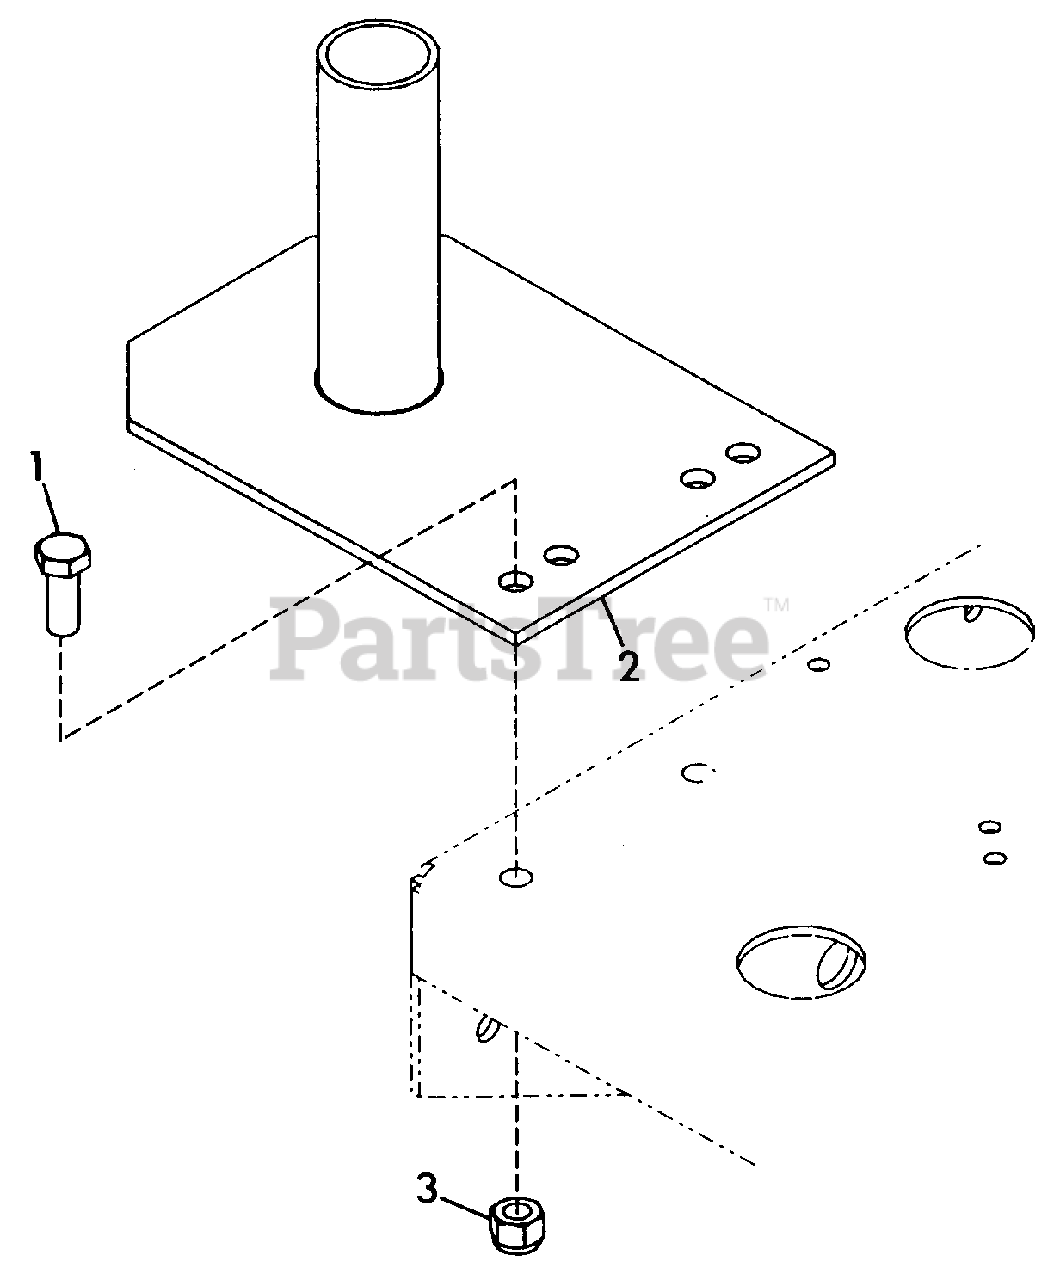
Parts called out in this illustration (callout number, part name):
1	BOLT, HEX 1/2-13X1.25
2	WELDMENT, WEIGHT RACK
3	NUT, LOCK 1/2-13
